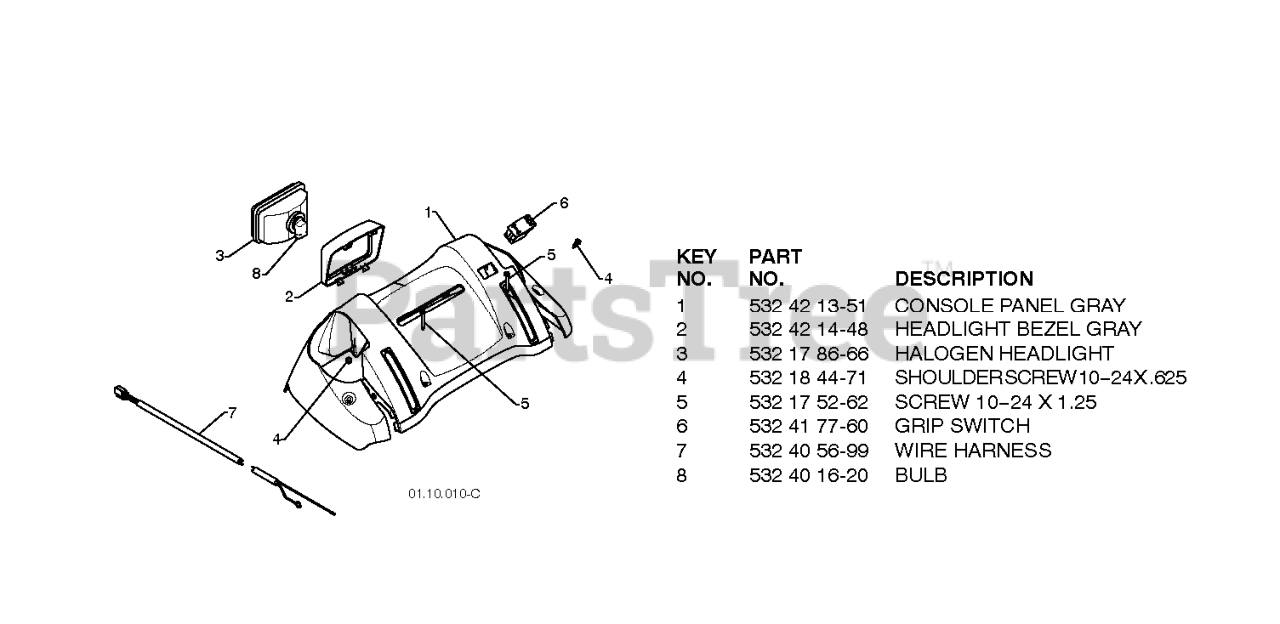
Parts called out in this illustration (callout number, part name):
1	PANEL.CONSOLE.
2	BEZEL.HEADLIGHT
3	HEADLIGHT.HALOGEN.SNOW
4	SCREW, HEX HEAD, TAPPING
5	SCREW, HEX HD TAPPING #10-24 1
6	SWITCH.HEATED.GRIP
7	HARNESS.WIRE.LIGHT/GRIP.SNOW
8	BULB.HEADLIGHT.HALOGEN.
